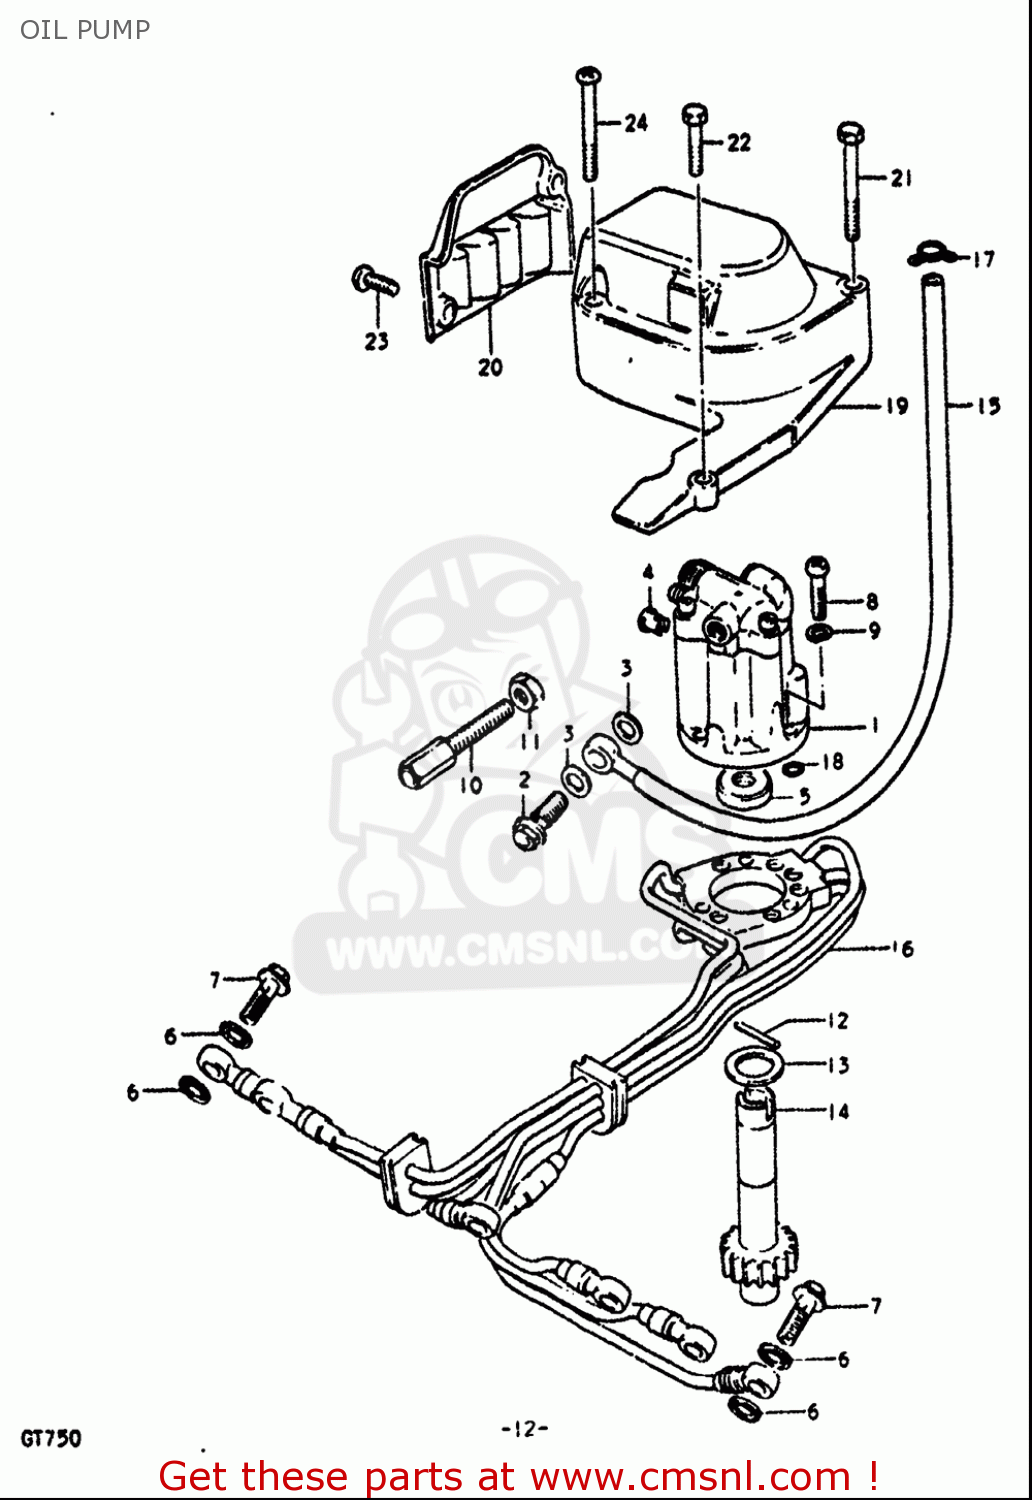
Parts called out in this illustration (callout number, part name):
2	UNION BOLT
3	GASKET(6.2X11X1).2 (NAS)
4	TERMINAL,CABLE
5	SEAL,OIL(8X16X4)
6	GASKET(6.2X11X1).2 (NAS)
7	UNION BOLT
8	SCREW
9	WASHER,LOCK
10	BOLT
11	NUT
12	PIN(3X13.8)
13	SHIM(14X22X1)
15	HOSE,INLET
17	CLAMP
18	O RING(D:1.9,ID:3.8)
21	BOLT 5X45
22	BOLT 5X20
23	SCREW
24	SCREW
